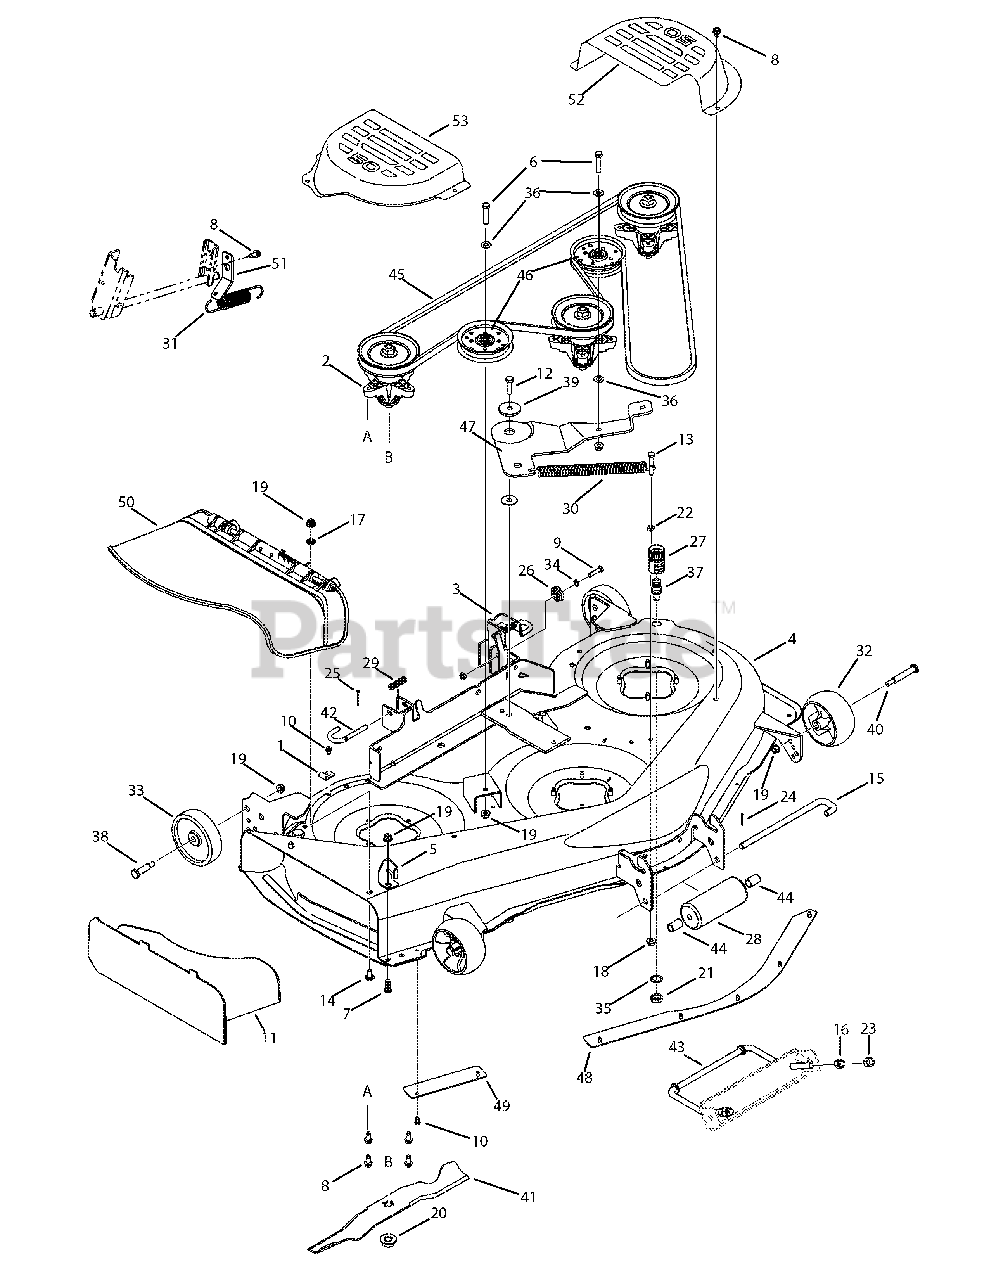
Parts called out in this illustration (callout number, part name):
1	Hook, Retainer
2	Spindle Assembly
6	Screw, 3/8-16, 1.75
7	Screw, 3/8-16 x 1.0
8	Screw, 5/16-18 x .75
9	Screw, 5/16-18, 1.25, Gr5
10	Screw, 1/4-20 x 0.5
11	Mulch Plug, 50" Deck
12	Screw, 3/8-16, 1.25
13	Screw, 5/16-18 x 2.00
14	Screw, Carriage, 3/8-16 x .75
16	Hex Nut, 1/2-13, Gr5
17	Push Nut, 3/8
18	Nut, Nylon Lock, 5/16-18
19	Nut, Nylon Lock, 3/8-16
20	Nut, Hex, Flange, 5/8-18
21	Nut, Hex, M16-1.5
22	Nut, Hex, 5/16-18, Gr5
23	Nut, Hex, 1/2-13, GrB
24	Pin, Cotter, 3/32, 1.0
25	Pin, Cotter, 1/8 x 1.25
26	Deck Adjustment Gear
27	Coupler, Hose
28	Roller
29	Spring, Compression, .531 x 1.75
30	Spring, Extension, .94 x 6.74
31	Spring, Extension, 1.15 x 5.99
32	Deck Wheel, 5.0
33	Deck Wheel, 5.0
34	Washer, Lock, 5/16
35	Washer, Lock, 5/8 Internal tooth
36	Washer, Flat, .406 x .875 x .059
37	Port, Water
38	Shoulder Screw, .496 x 1.525, 3/8-16
39	Spacer, Shoulder, .884 x .190
40	Shoulder Screw, .496 x 2.50, 3/8-16
41	Blade, 17.90 Lg. Star hole, 2 in 1
42	Rod, Deck Release .375 Dia.
43	Rod, Deck .5" Dia. (50-inch Decks)
44	Spacer, .550 x .755 x 1.1
45	Belt, V-Type
46	Pulley, Idler, 3.5"
50	Chute Assembly, Side Discharge
51	Lift Bracket, 50" Deck
